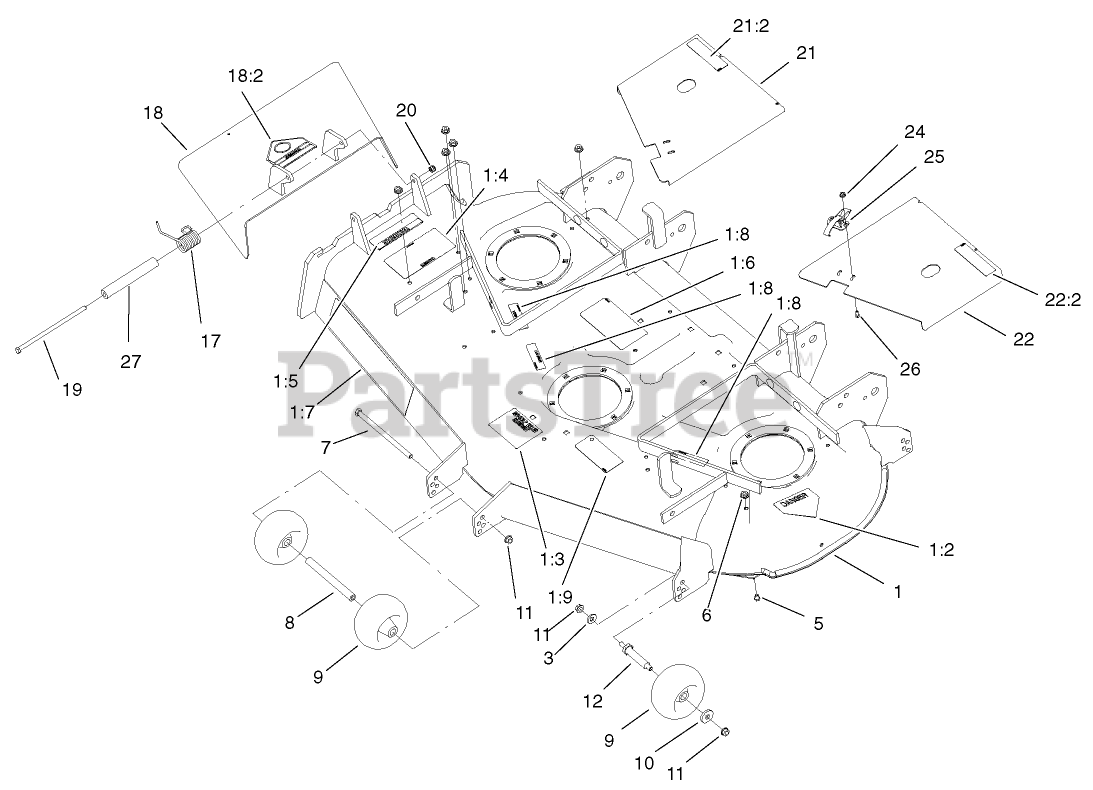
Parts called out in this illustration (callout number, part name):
1	Deck ASM
1:2	DECAL-DANGER
1:3	DECAL-WHEEL, GAGE
1:4	DECAL-DANGER, THROWN OBJECT
1:5	DECAL-WARNING
1:6	DECAL-BELT ROUTING
1:7	DECAL
1:8	DECAL-COVER, MISSING
1:9	DECAL-TORQUE, BLADE BOLT
3	WASHER-BELLEVILLE
5	SCREW-HH
6	NUT-HF
7	SCREW-HH
8	SPACER-WHEEL
9	WHEEL-GAGE
10	WASHER
11	NUT-HHF, WHIZ
12	SPACER
17	SPRING-TORSION
18	DEFLECTOR ASM
18:2	DECAL-DANGER
19	SCREW-HH
20	NUT-LOCK, NI
21	COVER ASM-RH
21:2	DECAL-DANGER
22	LH COVER ASM
22:2	DECAL-DANGER
24	NUT-LOCK, FLANGE
25	CLAMP-SLOTTED
26	SCREW-HWH
27	SPACER-MOUNTING, DEFLECTOR
